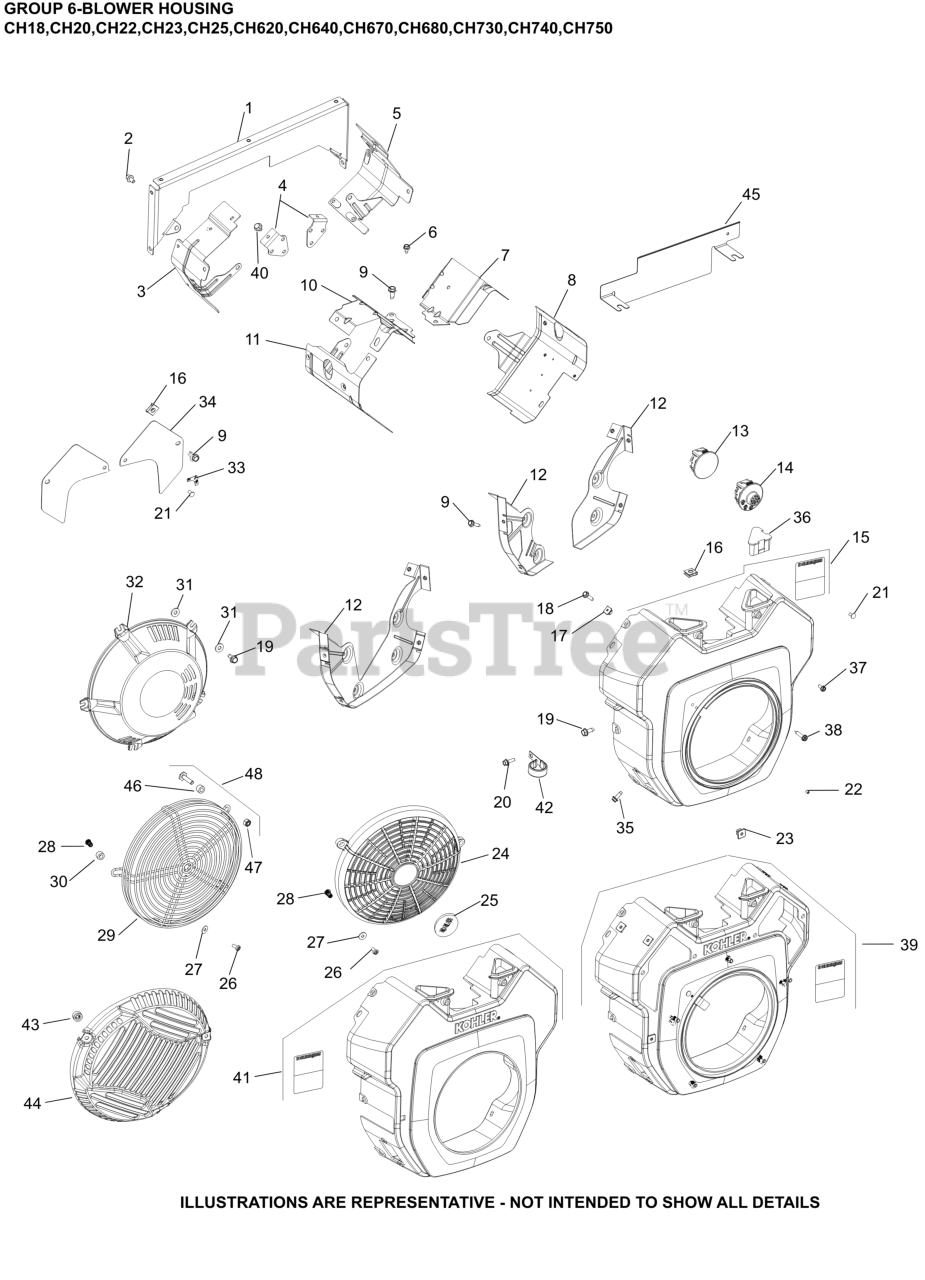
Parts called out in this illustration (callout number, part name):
6	SCREW, THREAD FORMING
7	BAFFLE, VALLEY #1 CYLINDER
8	KIT, CYL BAFFEL #1 SIDE
9	SCREW, THREAD FORMING
10	BAFFLE, VALLEY #2 CYLINDER
11	BAFFLE, LEFT BARREL
12	KIT, BACKING PLATE
19	SCREW, THREAD FORMING
35	SCREW, THREAD FORMING
NI	KIT, BLOWER HOUSING
